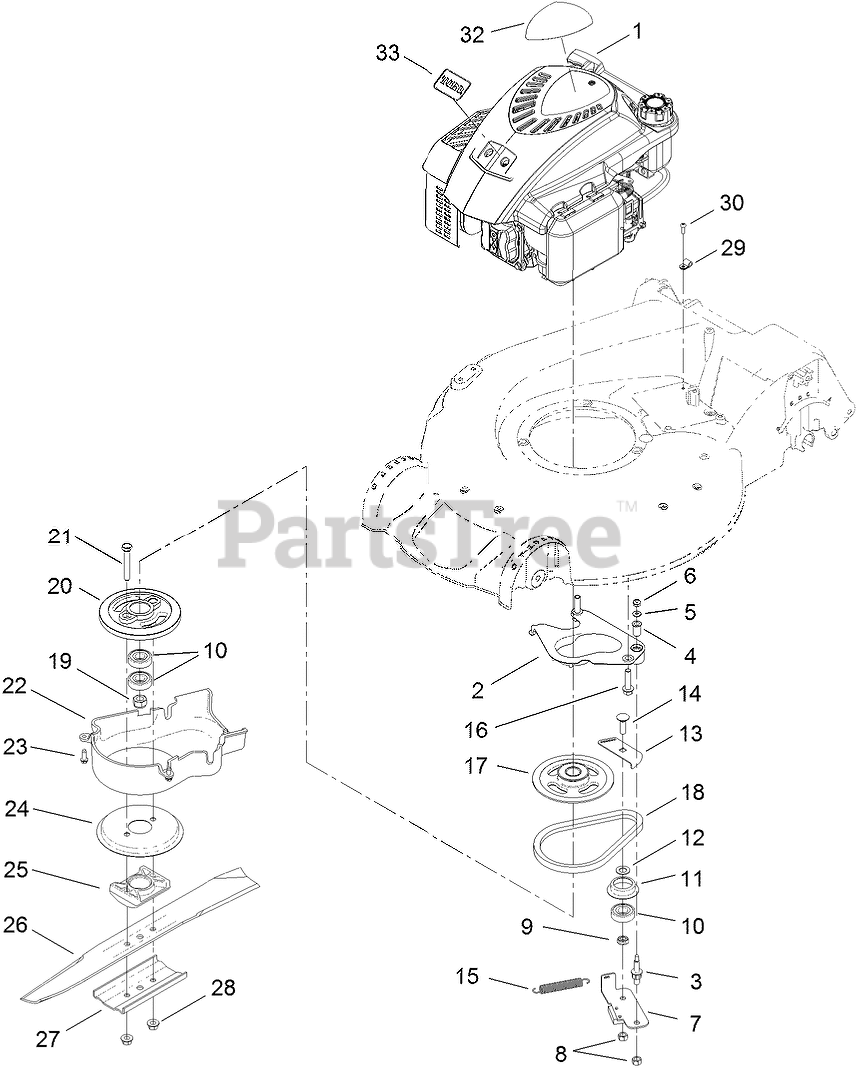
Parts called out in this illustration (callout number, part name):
1	ENGINE-1P65FA
2	PLATE-ANCHOR
3	BOLT-SHOULDER
4	BUSHING
5	WASHER-FLAT
6	NUT-LOCK, NI
7	BRAKE ARM ASM
9	SPACER-BEARING
10	BEARING-BALL
11	RETAINER-BELT
12	WASHER-PLAIN
13	PLATE-GUIDE
14	BOLT-CARR
15	SPRING-TENSION, BRAKE
16	SCREW-HWH
17	PULLEY
18	BELT
19	NUT-HEX
20	DRUM
21	SCREW-HH
23	SCREW-HWHTF
24	DISC
25	SUPPORT-BLADE
26	BLADE-RECYCLING
27	SUPPORT-BLADE
28	NUT-LOCK
29	CLAMP
32	DECAL-SHROUD
